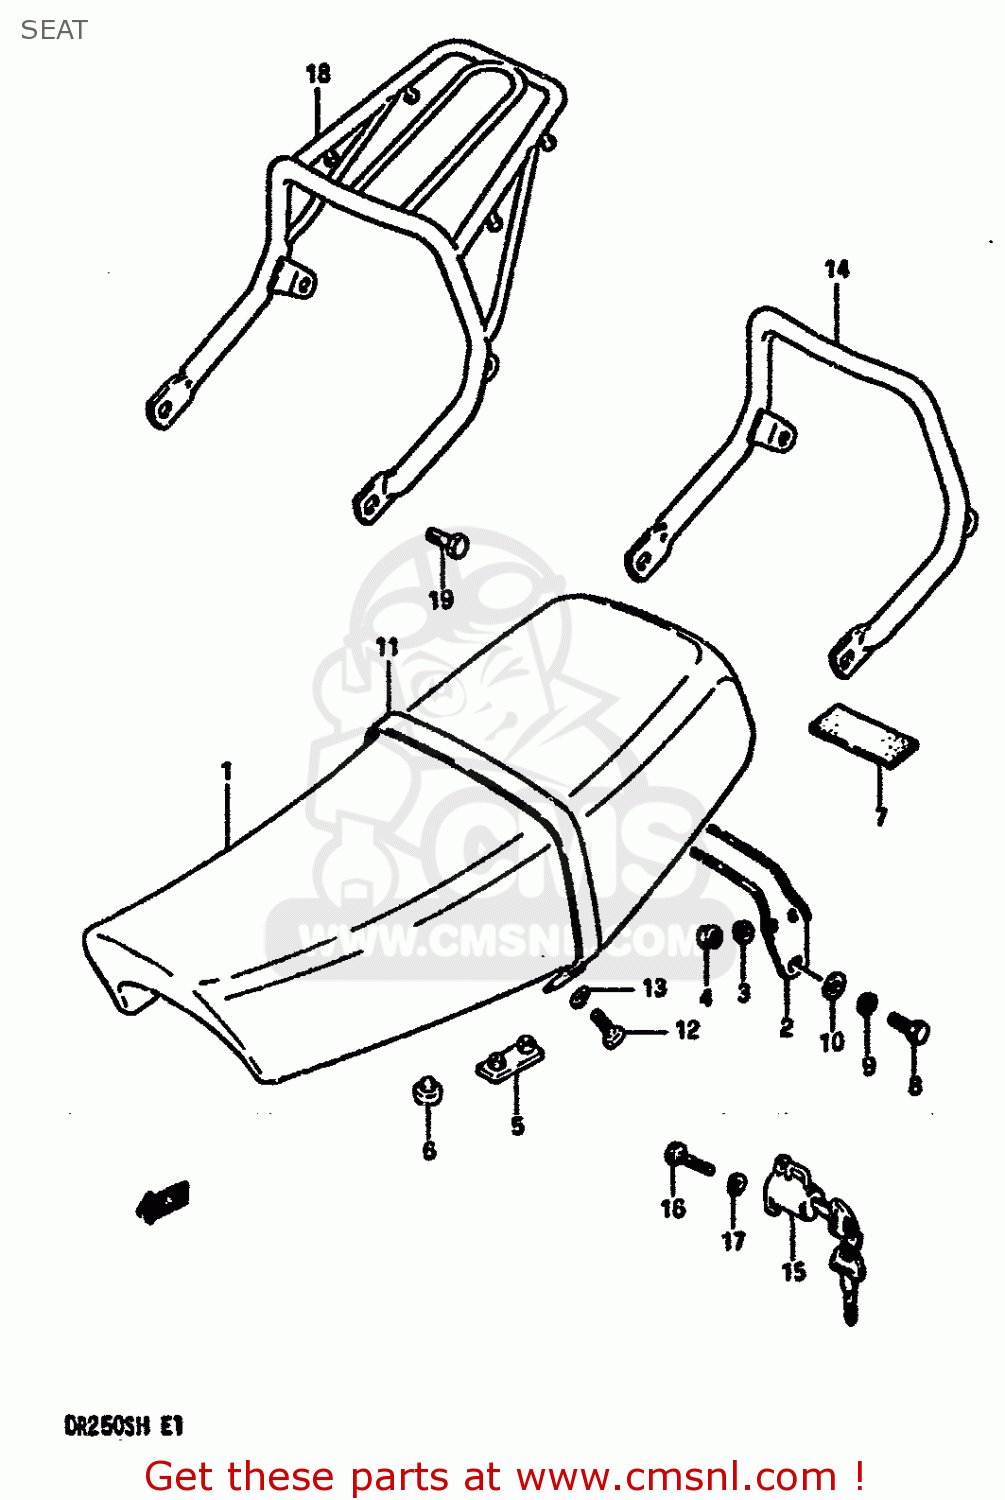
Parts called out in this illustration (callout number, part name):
1	SEAT ASSY (BLUE)
2	STAY,REAR
3	WASHER,LOCK
4	NUT
5	CUSHION
6	CUSHION
7	TAPE, SEAT UNDER
8	BOLT
9	WASHER,LOCK,8.
10	WASHER
11	BAND,SEAT GRIP (BLUE)
12	BOLT
13	WASHER,LOCK,8.
14	HANDLE, PILLION RIDER
15	LOCK ASSEMBLY,HELMET
16	BOLT 6X11
17	WASHER,LOCK
18	CARRIER
19	BOLT
